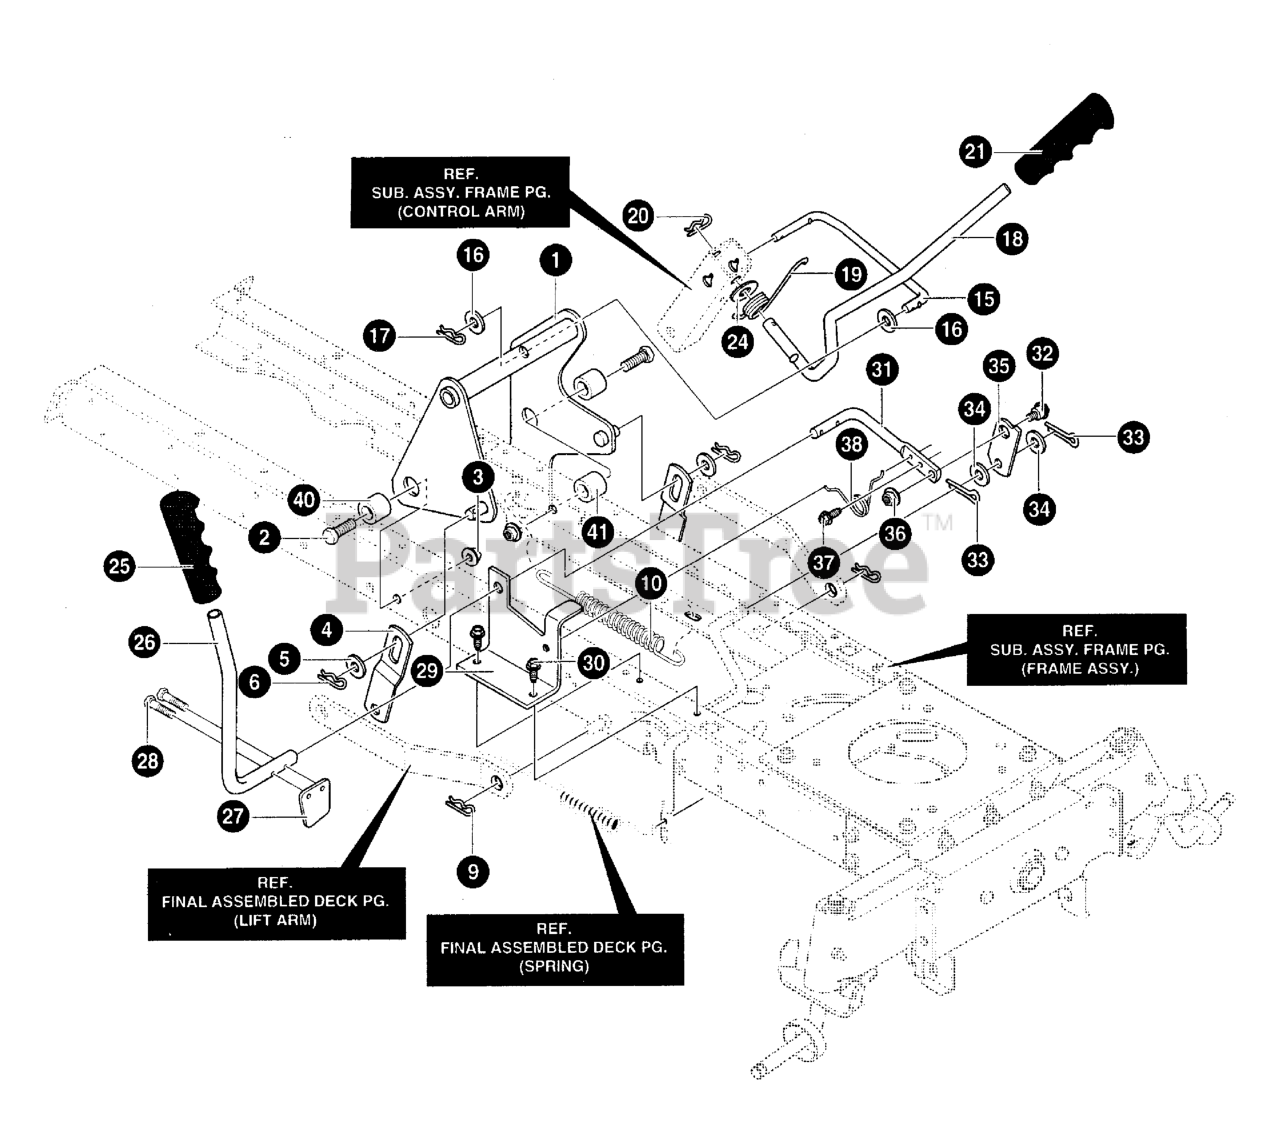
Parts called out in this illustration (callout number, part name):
1	ASSEMBLY, LIFT ARM
2	SCREW, 1/2-13X1.50
3	NUT, 1/2-13 LOCK
4	BRACKET, LIFT LINK
5	WASHER, FLAT
6	HAIR PIN.38DIAX1.64LG
9	HAIR PIN.38DIAX1.64LG
10	SPRING, EXTENSION 9.82X1.01 OD
15	LINK - LIFT HANDLE
16	WASHER, FLAT
17	HAIR PIN.38DIAX1.64LG
18	HANDLE, LIFT
19	TORSION SPRING
20	HAIR PIN.38DIAX1.64LG
21	GRIP, LIFT
24	WASHER, FLAT .550X1.00X11
25	Grip, PTO
26	PTO HANDLE
27	ZINC PADDLE, SWITCH
28	SCREW, THREAD FORM
29	BRACKET, PTO
30	SCREW, 5/16-18 x 0.50
31	ZINC LEVER, PTO
32	BOLT, .50X.75 HHSH 3/8-16
33	HAIR PIN
34	WASHER, FLAT .518 x .87 x 16
35	ZINC LINK PTO
36	NUT, 3/8-16 HWDFLLK MACK
37	SCREW, 5/16-18 x 0.75
38	TORSION SPRING
40	SPACER
41	SPACER, SLEEVE
